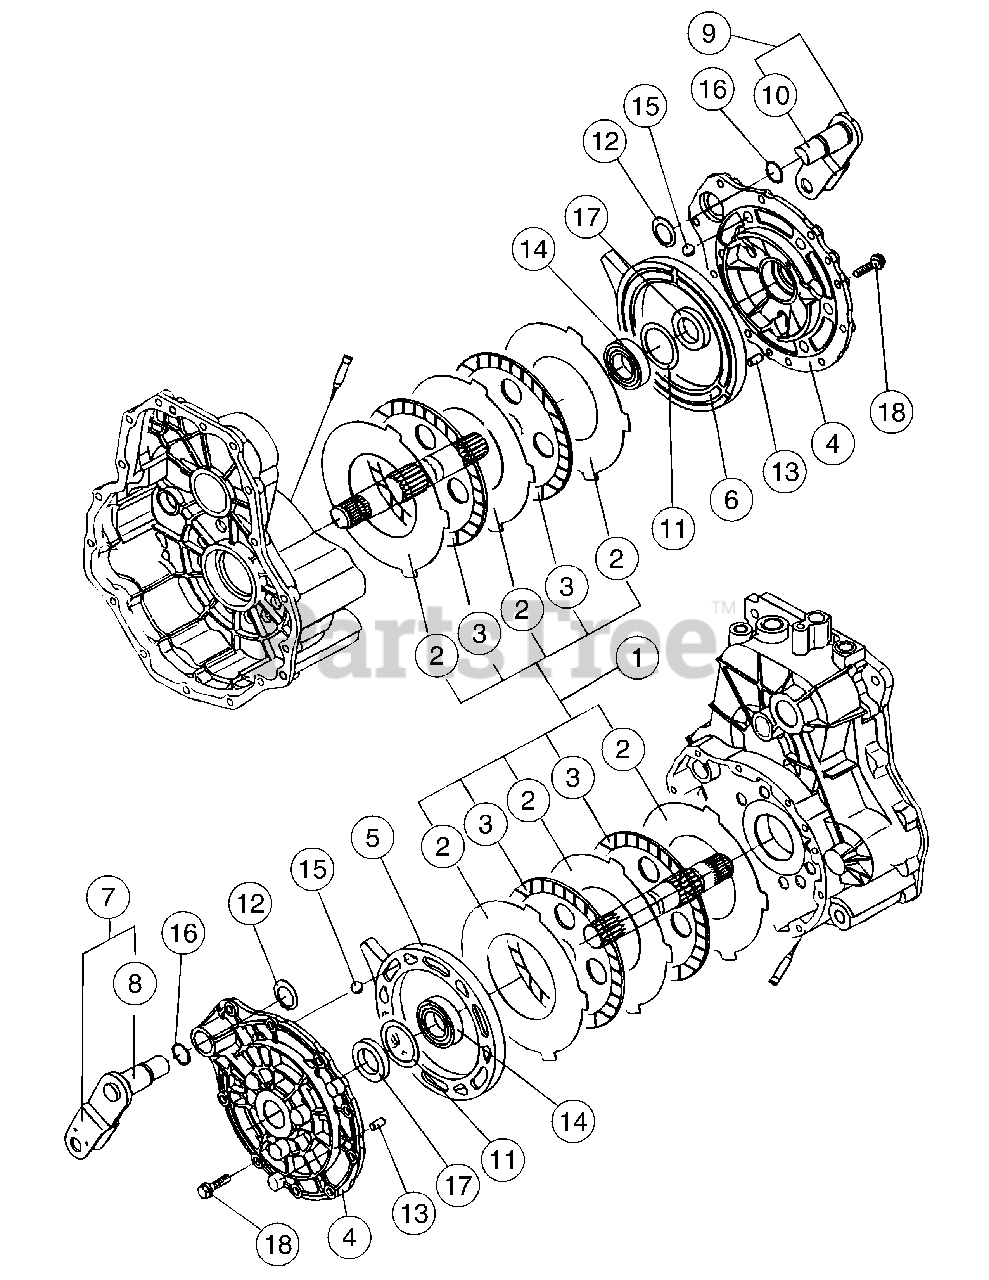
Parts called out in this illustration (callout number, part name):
2	Steel Plate
3	Friction Plate, 175
7	Cam Lever, Complete, LH
8	Cam Lever Shaft
9	Cam Lever, Complete, RH
10	Cam Lever Shaft
11	Washer, 42 x 54.6 x 1
14	Bearing, 6006
16	Packing, P 21
17	Seal, TC304708
18	Tapping Screw, 8 x 30
18	Flange Bolt, M8 x 30
